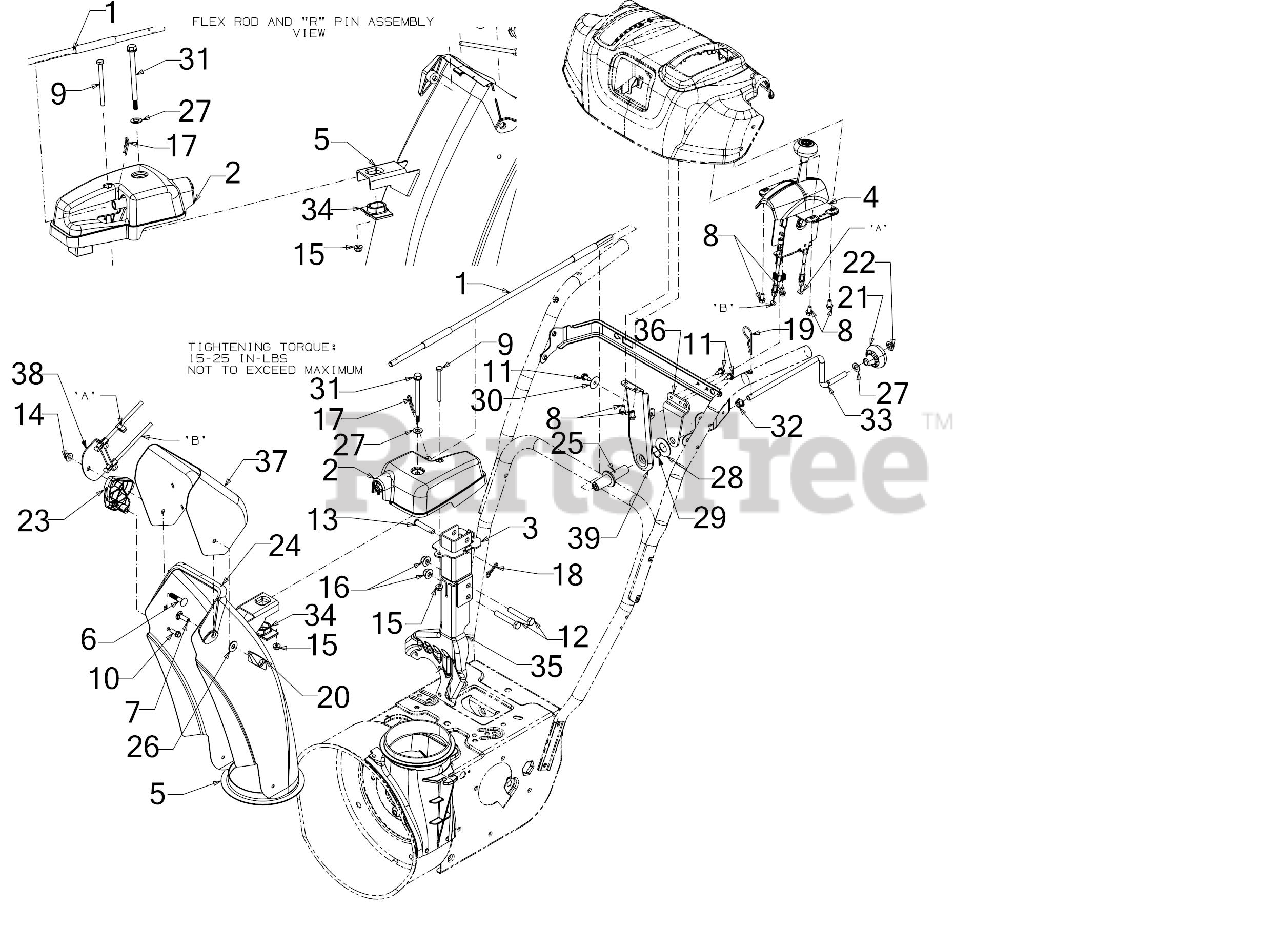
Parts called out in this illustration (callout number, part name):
1	CHUTE CONTROL SHAFT
2	WORM GEARBOX ASSEMBLY
3	CHUTE EXTENSION MAST
4	2-WAY TALL CHUTE CONTROL ASSEMBLY
5	LOWER CHUTE
6	CARRIAGE BOLT 5/16-18 x 1.50
7	CARRIAGE BOLT 5/16-18 x 1.00
8	HEX SCREW 1/4-15 x .50
9	SCREW 1/4-20 x 3.0 GR5
10	SCREW 1/4-15 x .750
11	SCREW 1/4-20X.625
12	SCREW 3/8-16 x 2.25 GR5
13	CLEVIS PIN 3/8 x 1.87
14	FLANGE LOCK NUT 5/16-18
15	FLANGE LOCK NUT
17	INTERNAL COTTER PIN
18	BOW TIE COTTER PIN 1/4-5/16
19	INTERNAL COTTER PIN
20	WING NUT KNOB
21	SHIFT KNOB
22	PUSH NUT
23	CHUTE TILT GUIDE
24	UPPER CHUTE ADAPTER
25	CHUTE ROD COUPLER
26	FLAT WASHER
27	FLAT WASHER
28	FLAT WASHER
29	WAVE WASHER .785X1.00X.012
30	FLAT WASHER
31	SHOULDER SCREW
32	BUSHING .380 ID
34	HELICAL GEAR CHUTE ADAPTER
35	CHUTE SUPPORT BRACKET
36	ROD SUPPORT BRACKET
37	UPPER CHUTE STEEL
38	CABLE BRACKET GUIDE
39	CHUTE CONTROL BRACKET
